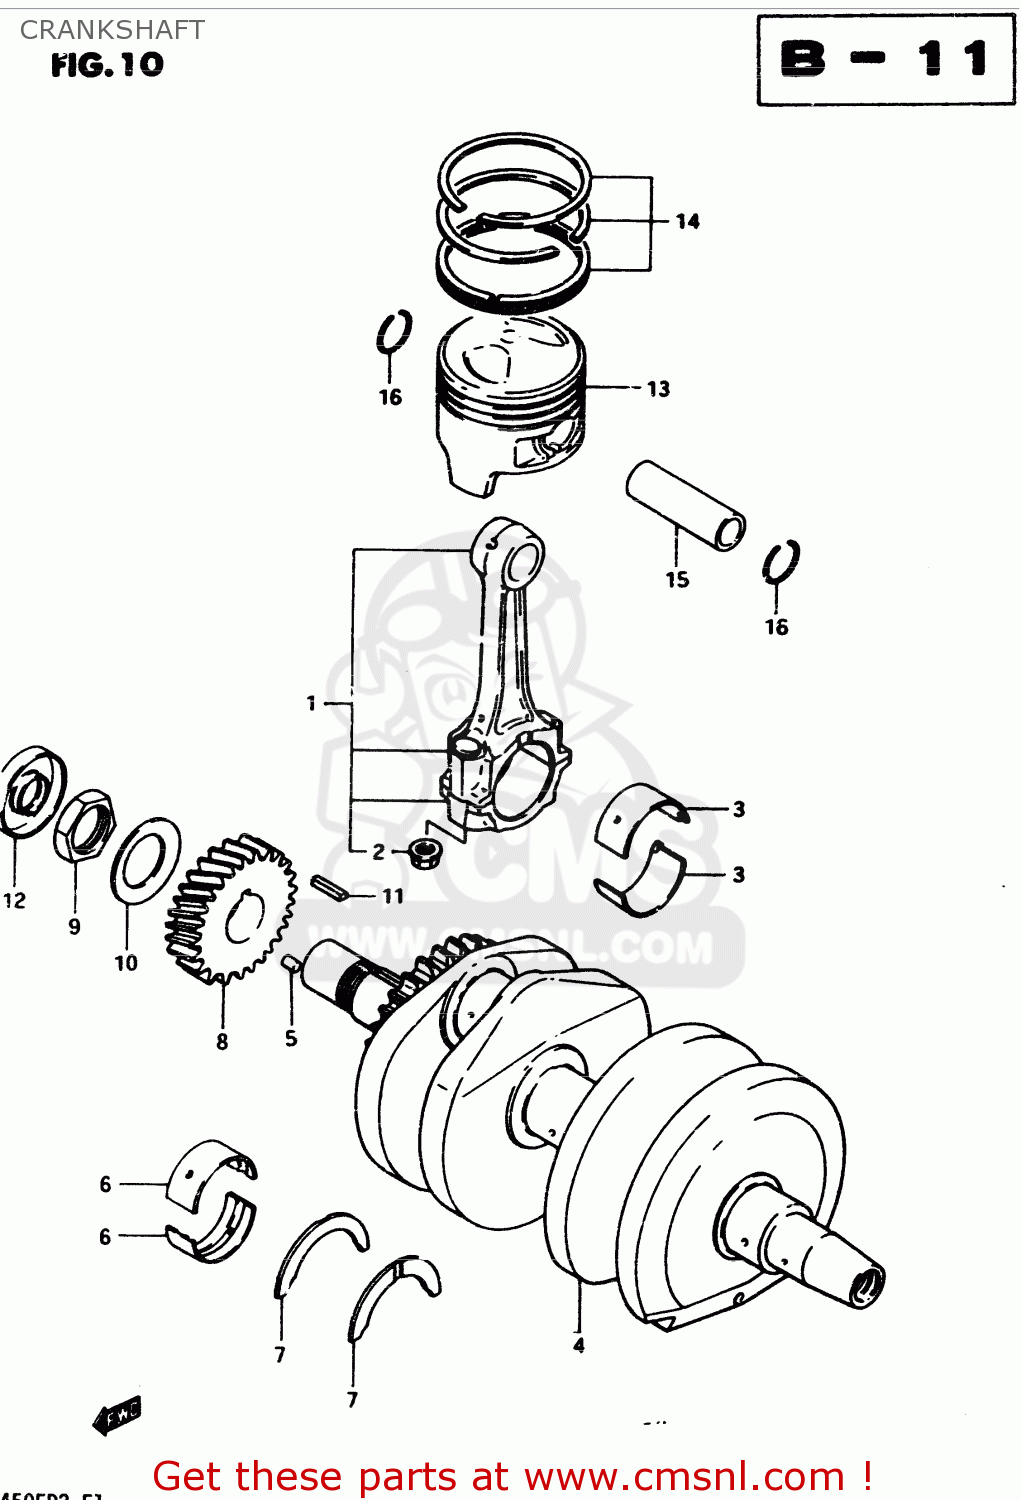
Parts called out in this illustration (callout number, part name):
1	ROD ASSEMBLY,CONNECTING
2	NUT
3	BEARING,CRANK PIN
4	CRANKSHAFT
5	PIN 3X5
6	METAL CRANKSHAFT
7	BEARING,CRANK THRUST
8	GEAR,PRIMARY DRIVE NO.28
9	NUT
10	WASHER
11	KEY
12	OIL SEAL
13	PISTON
14	RING SET,PISTON (OS:1.0)
15	PIN,PISTON (18MM)
16	CIRCLIP,PISTON PIN
